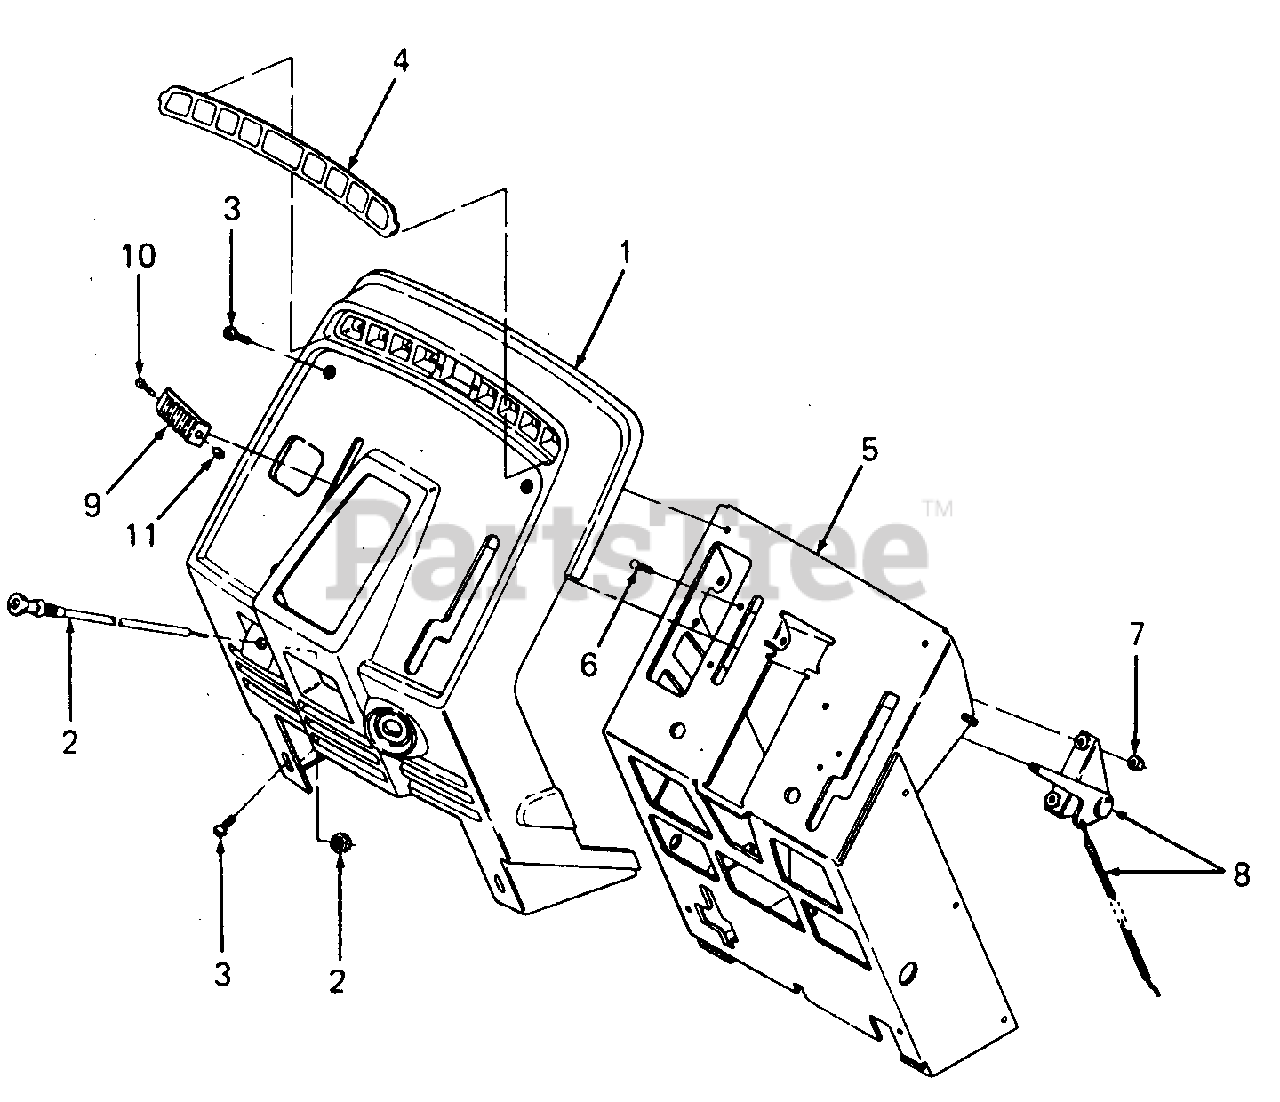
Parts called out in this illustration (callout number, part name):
1	Panel, Instrument
2	Choke Cable w/Nut
3	Screw, Pan Hd Cutting, #10-24 X .75 Lg
4	Label, Dash
7	Nut, Hex Keps, #10-32
8	Control, Throttle
9	Knob, Throttle
10	Screw, Cross Rec Truss Hd, #8-32 X .38 Lg
11	Nut, 8-32
